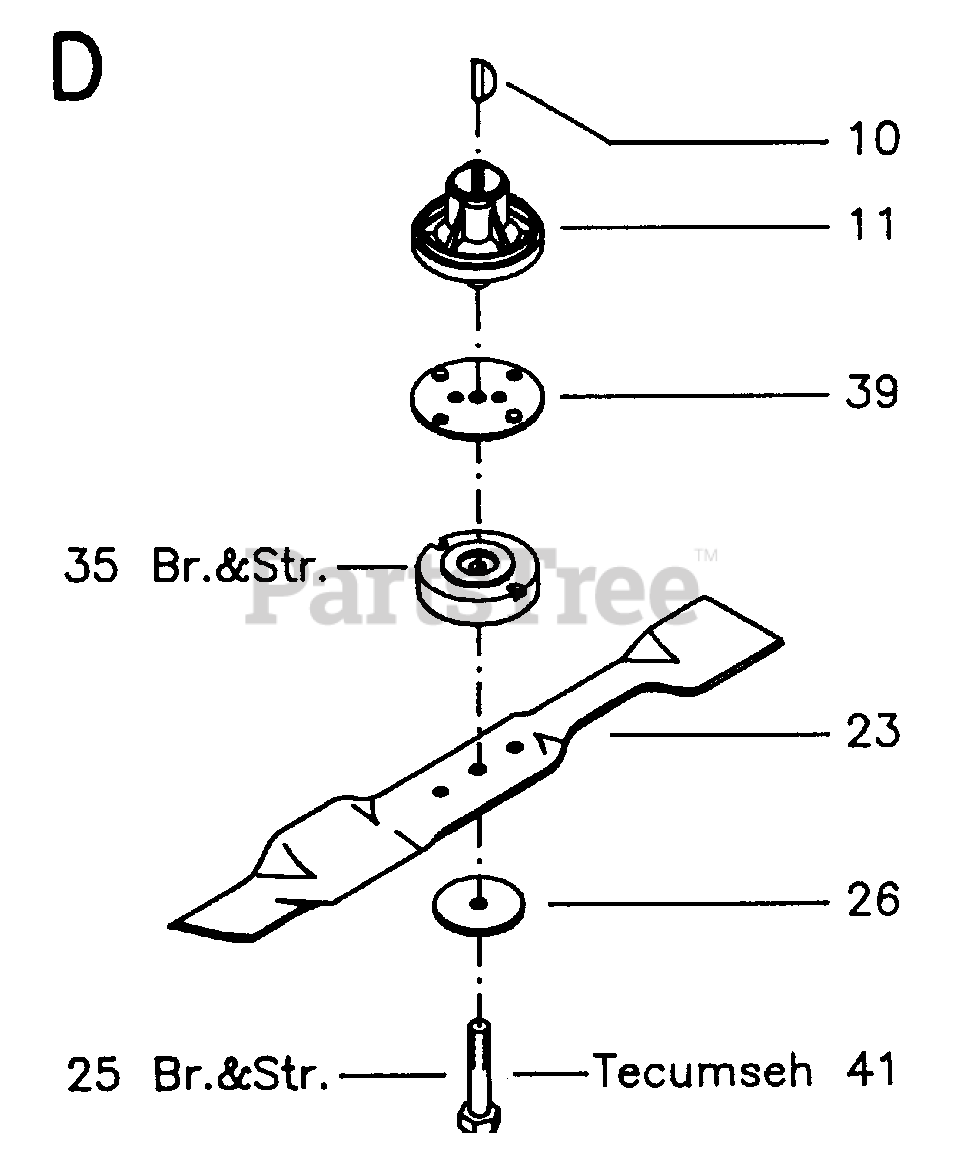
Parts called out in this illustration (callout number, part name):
11	BLADE ADAPTER
39	STEEL PLATE ADAPTER
41	REPL BY 515 12 39-31
